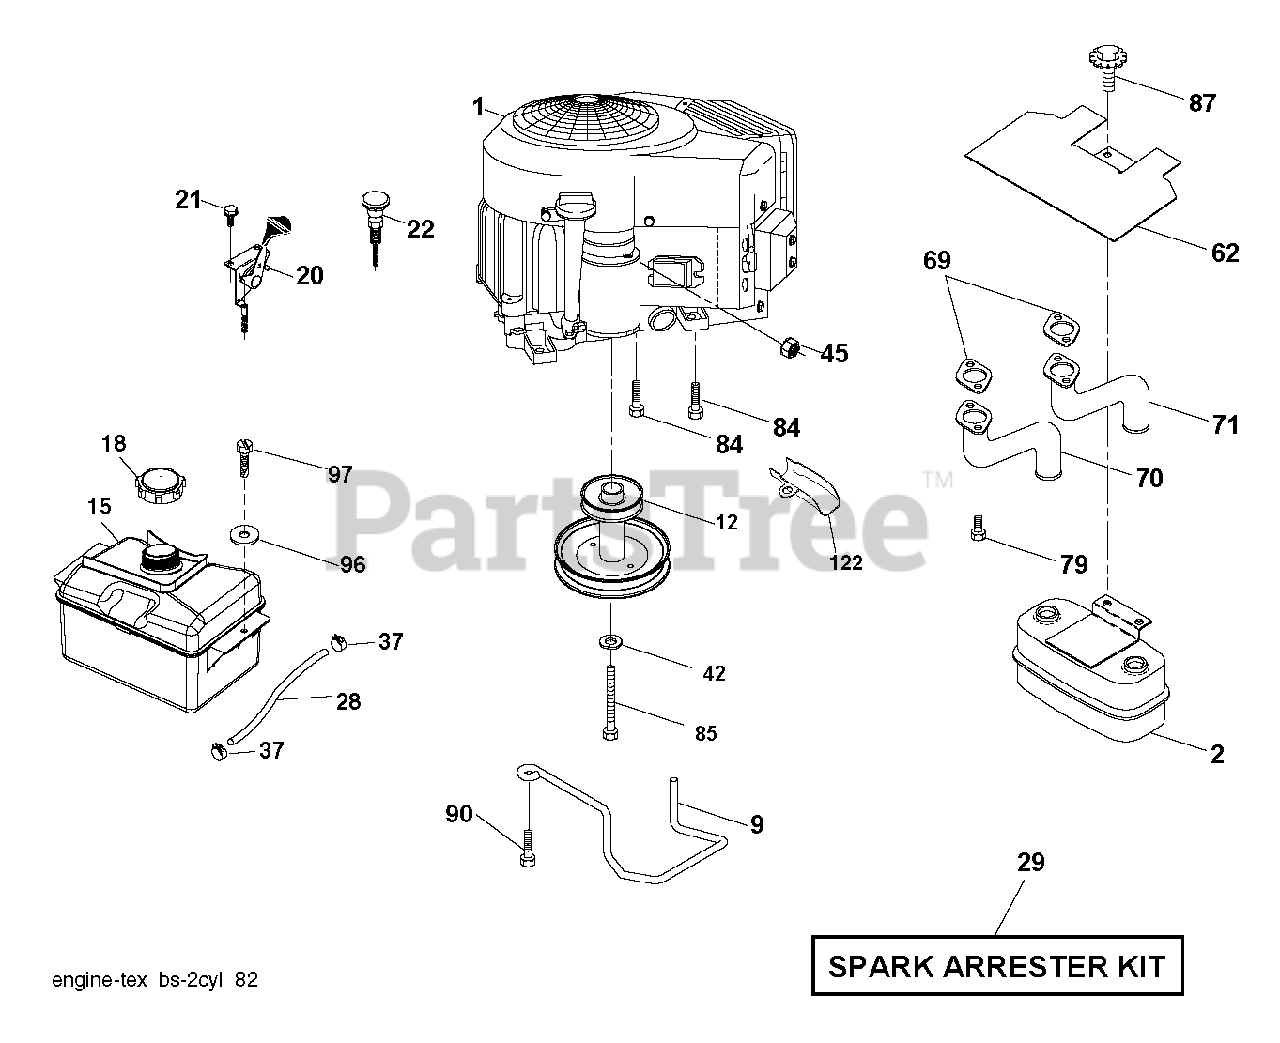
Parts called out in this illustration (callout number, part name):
2	MUFFLER.TWIN.CYL.LOW.TONE
9	KEEPER.BELT.ENGINE.4.2
12	PULLY ENGINE
18	CAP ASM.FUEL.2.25"FR.
20	THROTTLE CABLE
21	SCREW.#10 X 0.750.BOS THREAD
22	CONTROL CHOKE
28	LINE.FUEL.20
29	ARRESTER SPARK (OPTIONAL)
37	HOSE CLAMP
42	LOCKWASHER
45	NUT
62	SHIELD.HEAT.MUFFLER
69	GASKET.MUFFLER
70	TUBE MANIFOLD LH
71	EXHAUST TUBE RH
79	SCREW.SOCKET.HEAD.5/16-18
84	SCREW.3/8-16
85	BOLT HEX 7/16-20X4-1/4"
87	BOLT, 5/16-18 X 1 3/4
90	SCREW 3/8-16X1
97	SCREW HEXWSHR 1/4-20X3/4
122	EXTENSION DRAIN OIL
